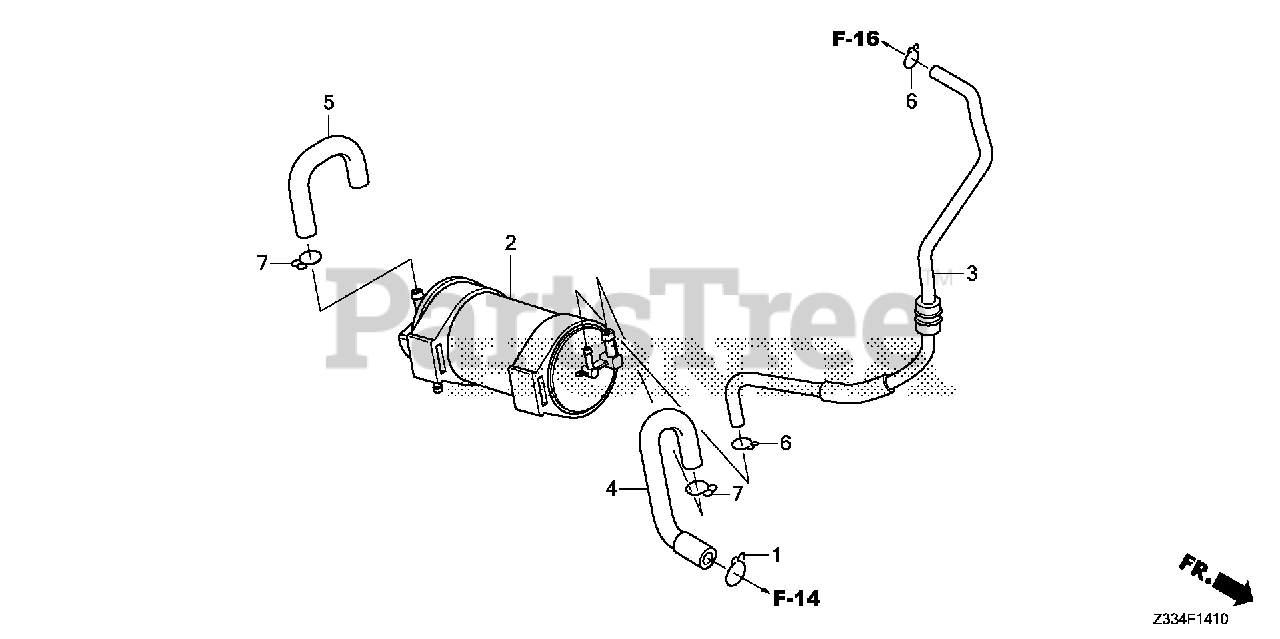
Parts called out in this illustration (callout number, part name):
1	CLIP, BREATHER TUBE
2	CANISTER ASSY.
3	TUBE CANISTER CHARGE
4	TUBE, CANISTER PURGE
5	TUBE, CANISTER AIR
6	CLIP, TUBE (B8)
7	CLIP, TUBE (B12)
